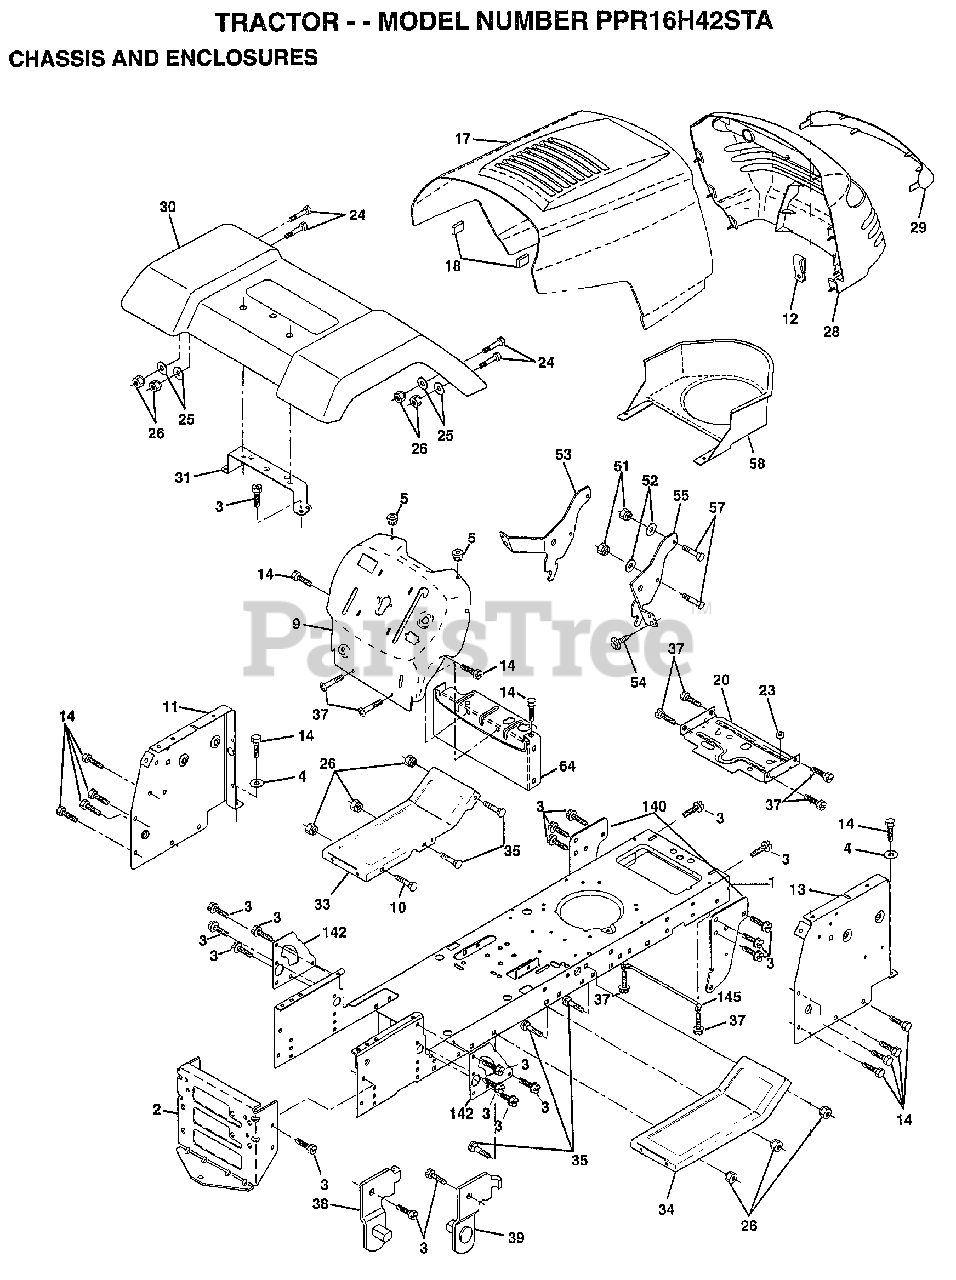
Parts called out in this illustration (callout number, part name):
1	CHASSIS.STLT.STAMPING
3	SCREW
4	WASHER
5	BUMPER-HOOD/DASH
11	"PANEL-DASH,LH"
12	CLIP.TINNERMAN
13	PANEL.ASM.DASH.RH
14	SCREW LT
17	"HOOD W/TRIM,MS428"
20	"PLATE-MTG,BATT/FU"
24	BOLT
25	WASHER
26	NUT
28	GRILL
29	GRILLE.LENS
30	FENDER.FOOTREST.SPLT.PNT
31	BRACKET SUPT FEND
33	FOOTREST PNT LH
34	FOOTREST.RH.LT/GT
35	BOLT
37	SCREW LT
38	BRACKET ASM LH
39	BRACKET ASM RH
51	NUT
52	WASHER
53	BRACKET.GRILLE.LH
54	SCREW.HEX.WS.HD
55	BRACKET.GRILLE.RH
58	AIR DUCT
64	DASH-LOWER
140	BRKT SUSPENSION
142	PLATE.REINFORCEMENT
145	"ROD POVOT,CHASSIS"
